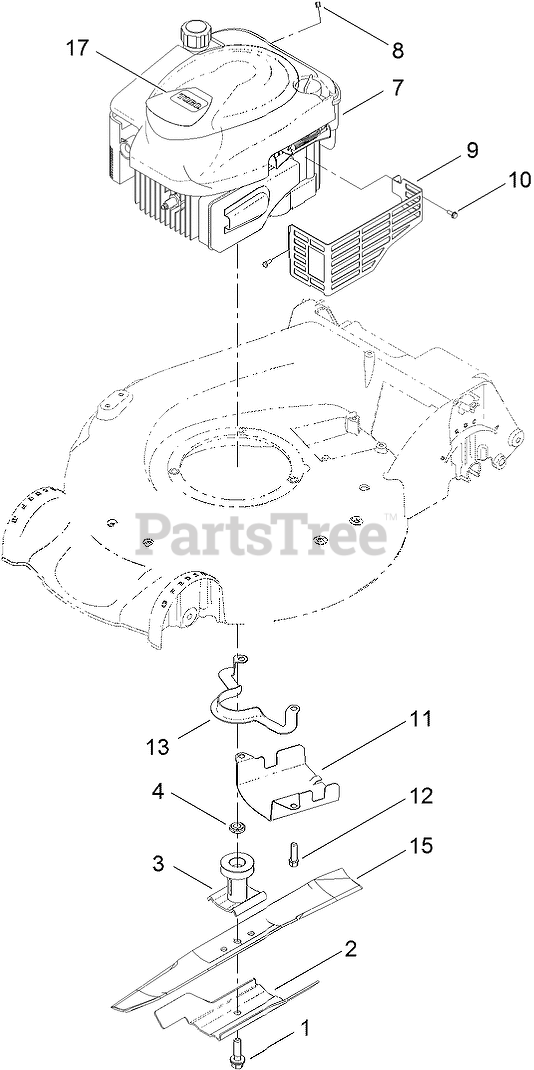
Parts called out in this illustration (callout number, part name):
1	BOLT-BLADE
2	Accelerator-Blade
3	DRIVER-BLADE
4	Spacer-Driver
8	STOP-ROPE
9	SHIELD-MUFFLER
10	SCREW-TAPTITE
11	SHIELD-GRASS
12	SCREW-TAPTITE
13	GUIDE-BELT
15	BLADE-RECYCLING
17	DECAL-SHROUD
